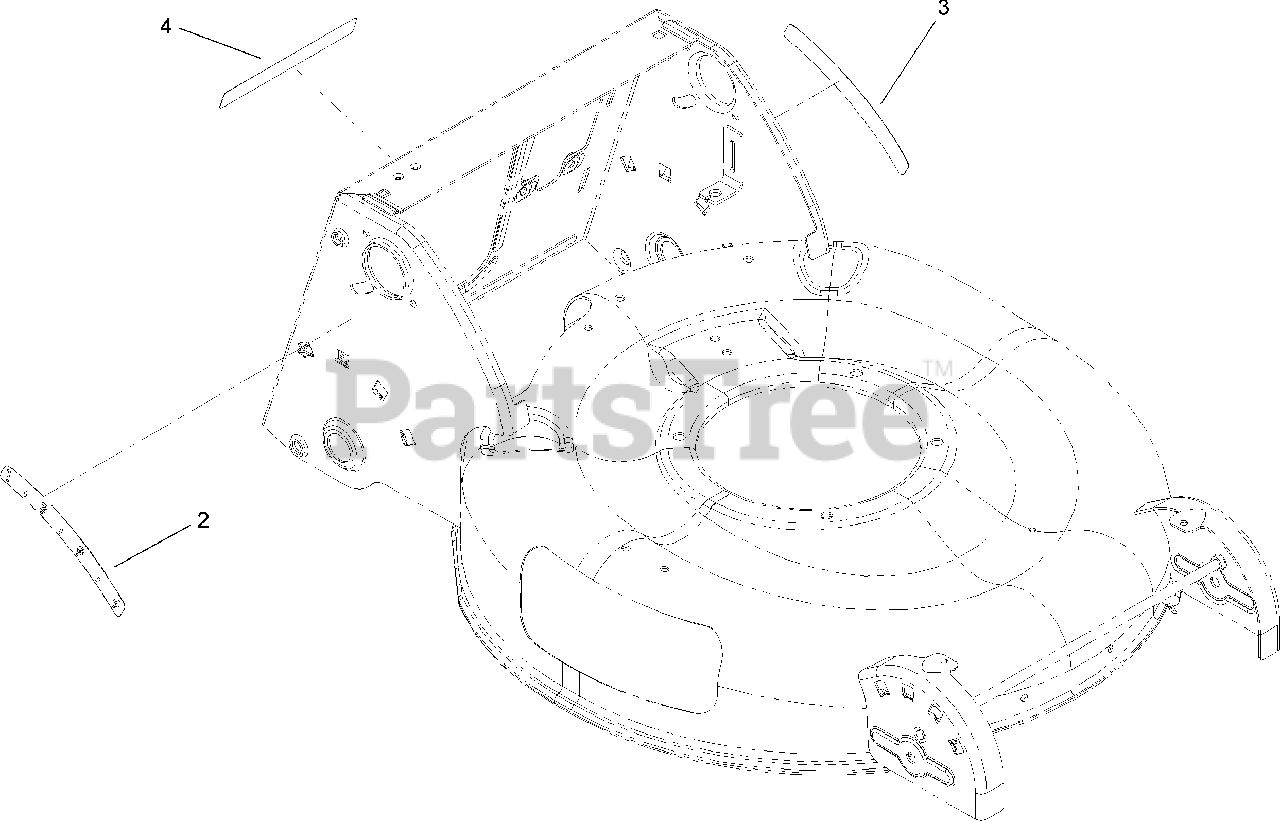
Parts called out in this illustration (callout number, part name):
2	DECAL-HOC, RH
3	DECAL-HOC, LH
4	DECAL-SAFETY, BAG (CE)
